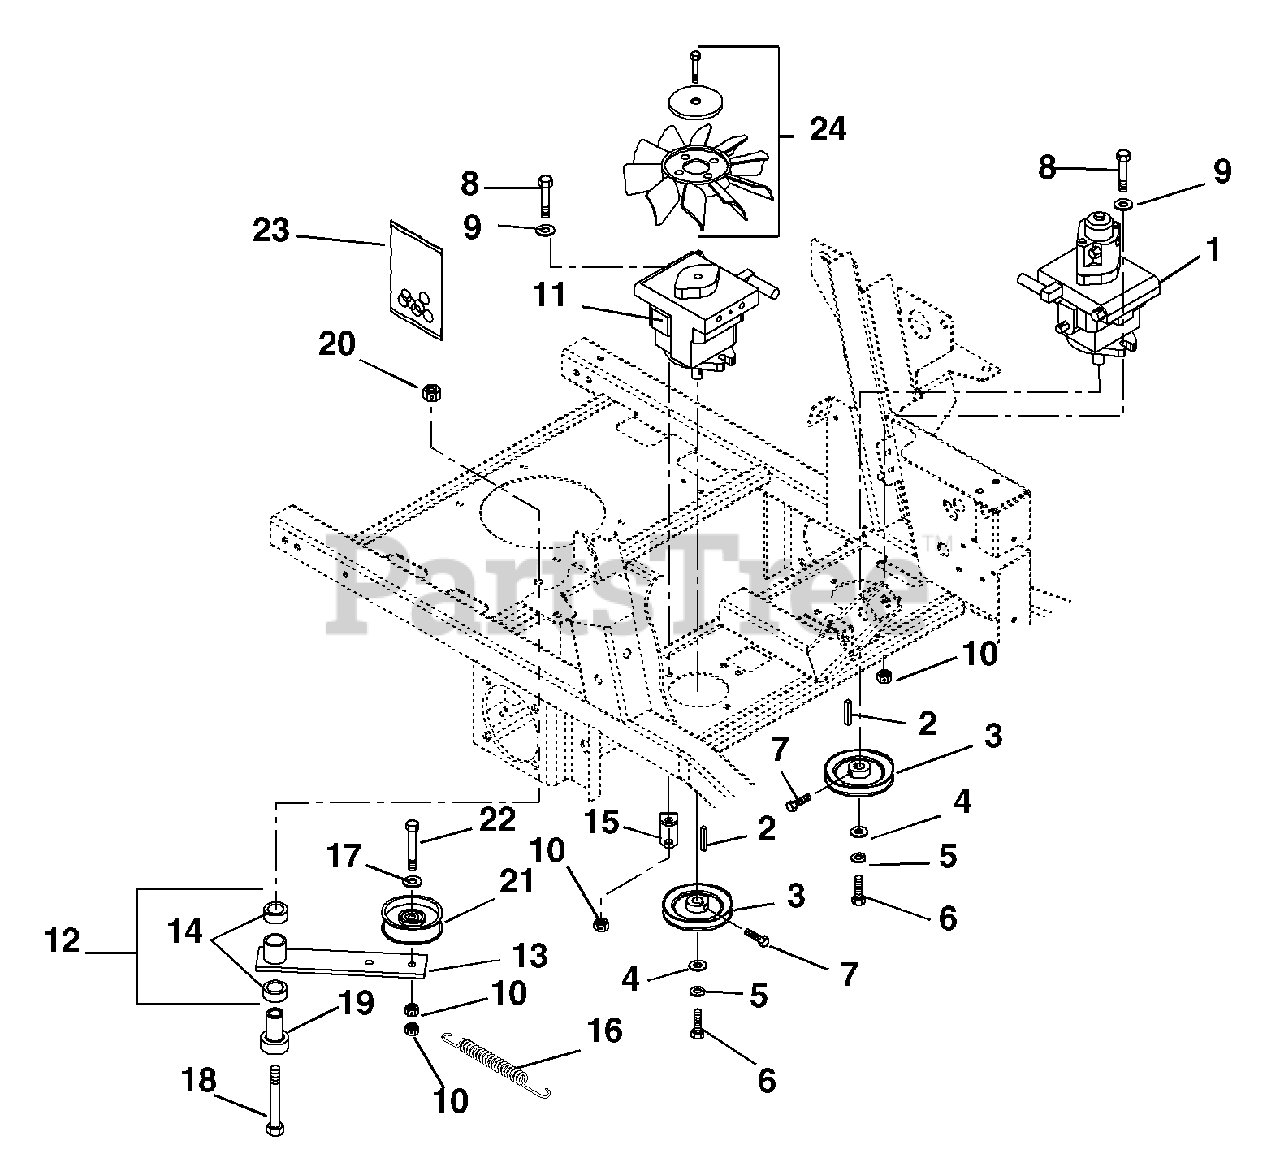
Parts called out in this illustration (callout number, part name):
1	Hydrostat BDP with Auxiliary
2	Key-Straight 5mm x 25mm x 5mm
3	Sheave 4.0 x .199
4	Washer-Flat-Steel .25 x 1.0 x .048
5	Washer-Locking .25 x .062
6	Bolt-Hex M6 x 1.0 x 12
7	Bolt-Hex .25-20 x .50 Grade 5
8	Bolt-Hex .38-16 x 1.25 Grade 5
9	Washer-Flat-Steel .390 x .75 x .125
10	Nut-Locking-Center .38-16
11	Variable-Displace Pump
12	Assembly,Idler Arm Guard Drive
13	Weldment, Idler Arm Ground Drive
14	Bearing, 1.00 x 1.12 x .75
15	Anchor-Spring-Idler
16	Spring-Tension .120 x .845 x 6.500
17	Washer-Flat-Steel .39 x.75 x.125
18	Bolt-Hex .50-13 x 3.50 Grade 5
19	Bearing, Pedestal Powdered Metal
20	Nut-Locking-Center .50-13
21	Assembly-Idler Pulley
22	Bolt-Hex .38-16 x 2.25 Grade 5
23	Kit, Pump Seal (BDP-10A)
24	Fan, Cooling
